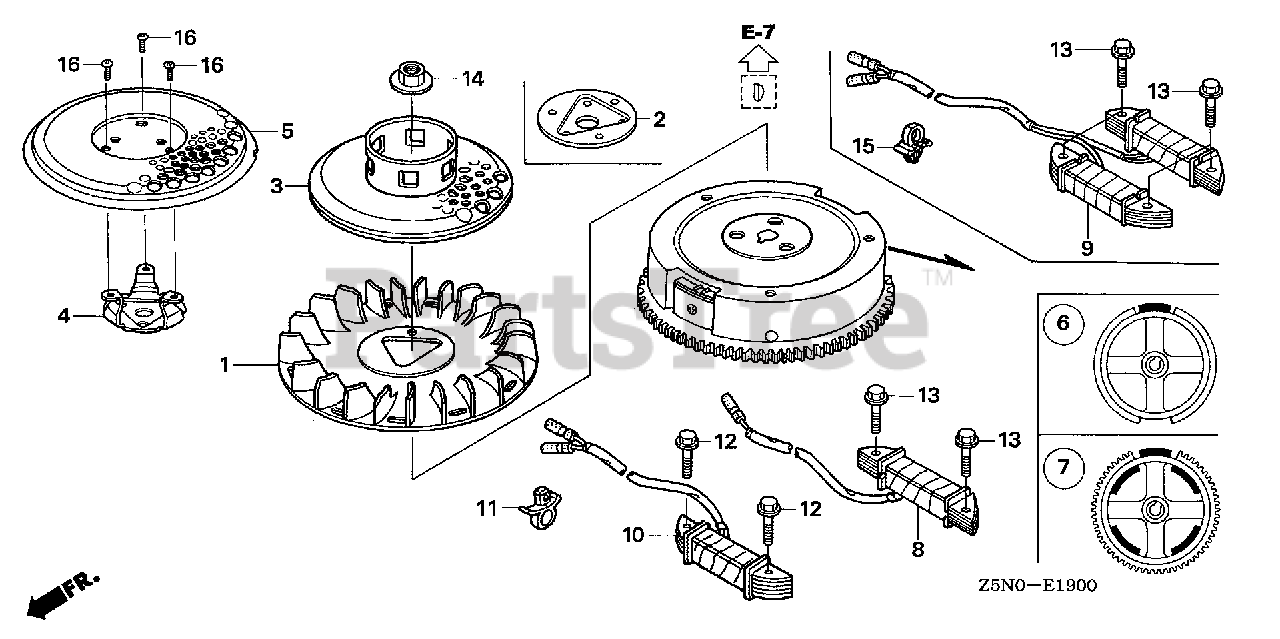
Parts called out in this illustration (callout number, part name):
1	FAN, COOLING
3	PULLEY, STARTER (SCREEN GRID)
7	FLYWHEEL (SEL-4POLE)
8	COIL ASSY., LAMP (12V70W)
10	COIL ASSY., CHARGE (1A)
11	CLIP, BRAKE PIPE (A)
12	BOLT, FLANGE (6X28) (CT200)
13	BOLT, FLANGE (6X32) (CT200)
14	NUT, SPECIAL (16MM)
